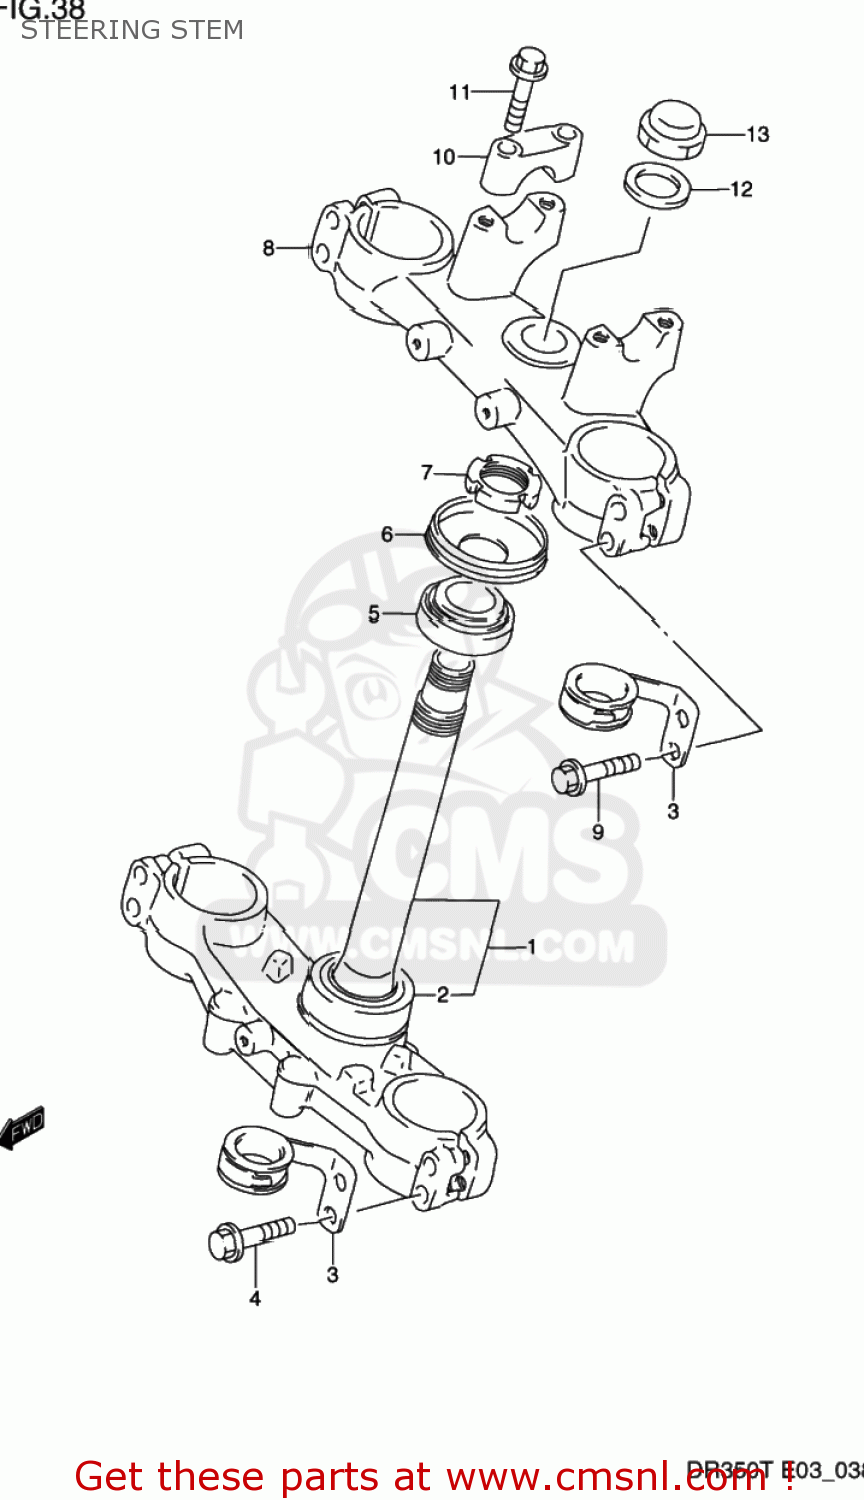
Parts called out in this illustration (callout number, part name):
1	STEM,STEERING
2	BEARING(30X55X17)
3	GUIDE,CABLE LWR,L
4	BOLT
5	TAPER,ROLLER BEARING
6	SEAL,STEERING UPR DUST
7	NUT,STEERING STEM
8	HEAD,STEERING STEM
9	BOLT
10	HOLDER,HANDLE UPR
11	BOLT
12	WASHER
13	NUT
